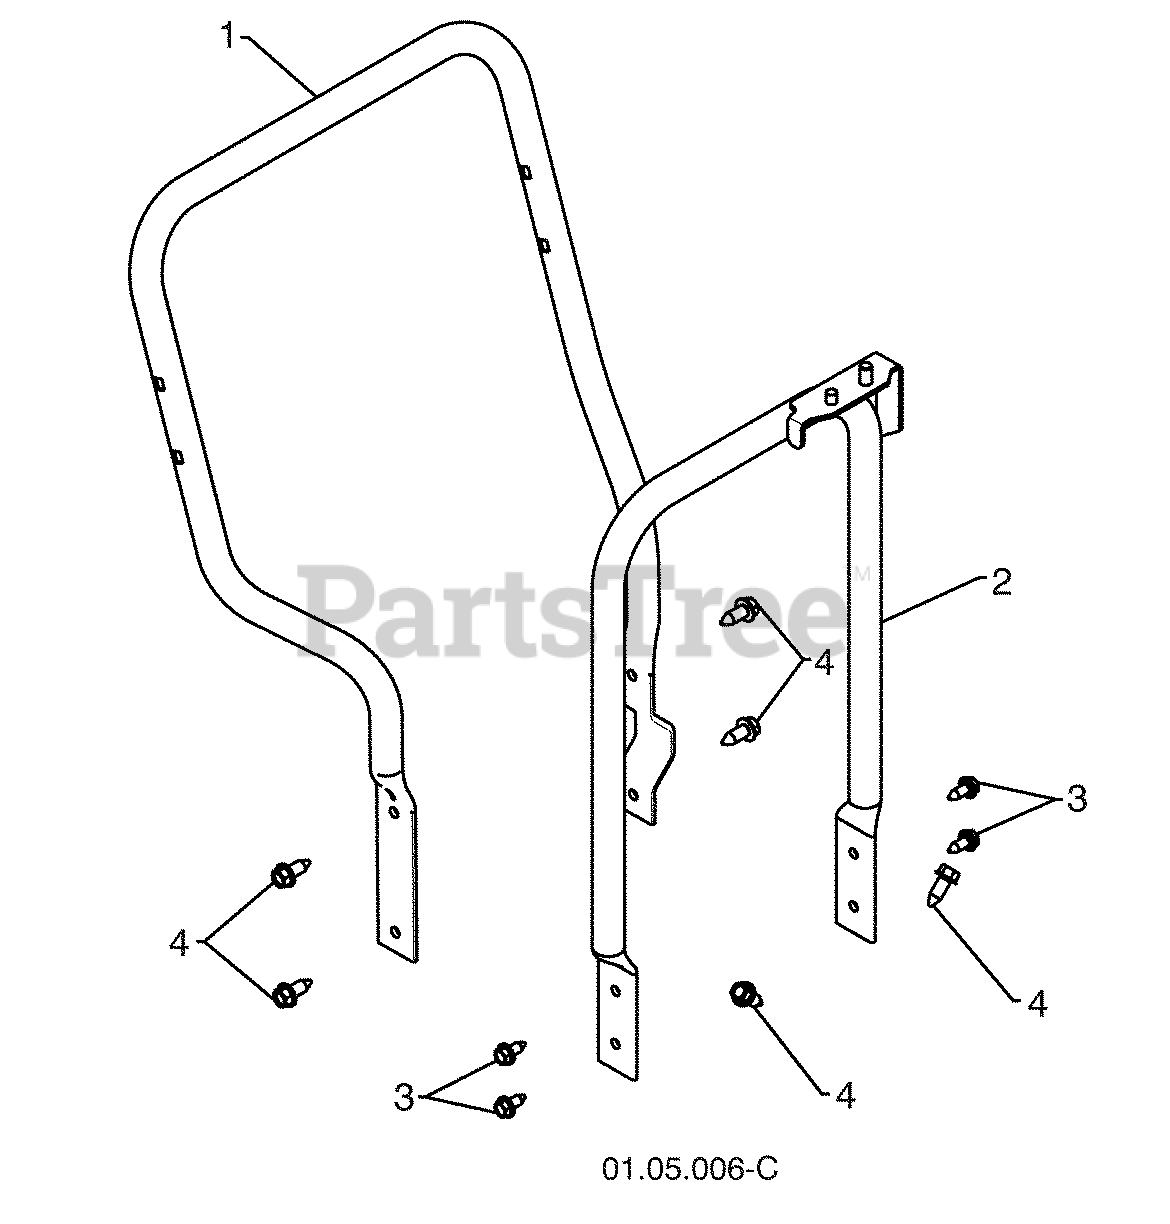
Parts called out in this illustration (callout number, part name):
1	LOWER TUBE GRAY
2	PIVOT SUPPORT
3	BOLT 5/16-18 X .750
4	SCREW 3/8-16 X 1.00
